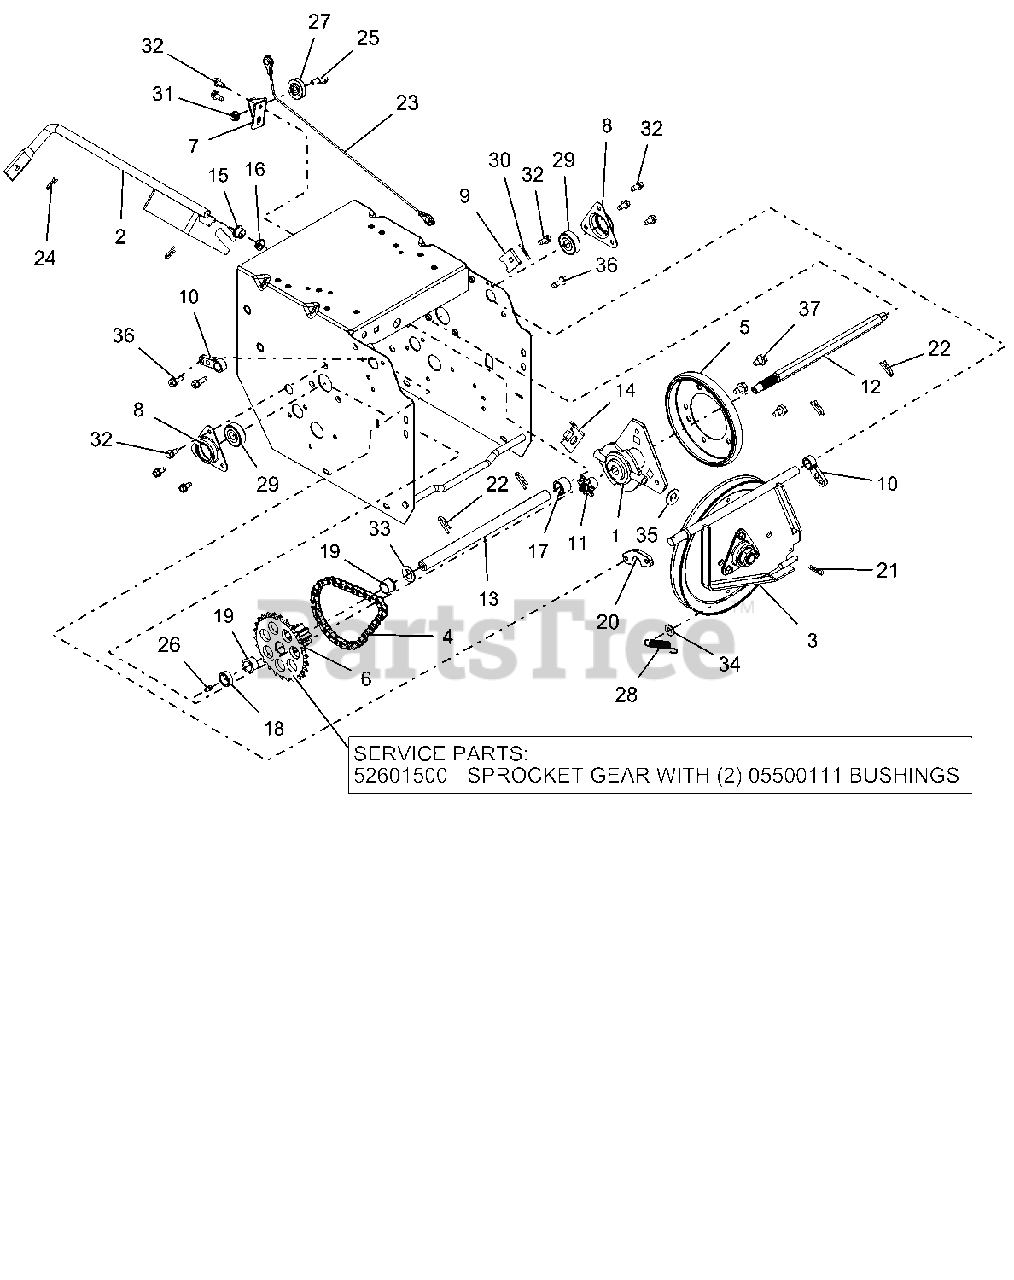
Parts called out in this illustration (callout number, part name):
1	CARRIER, DRIVE DISK
2	WELDMENT, SHIFT FORK
3	PLATE, SWING - ASSEMBLY
4	CHAIN - #41, 32 PITCHES
5	FRICTION, DISC
6	BSHG-FLG .625X.750X.500X.875
6	PINION & SPROCKET
6	PINION & SPROCKET W/BUSHINGS
7	BRACKET, CABLE PULLEY
8	FLANGE, BEARING
9	TAB, ANTI ROTATION
10	SUPPORT BUSHING, SWING GATE
11	SPROCKET, PINION 7T W/SPLINE
12	SHAFT, HEX W/SPLINE TRACK
13	SHAFT, PINION TRACK
14	BRACKET, FORMED - SHIFT FORK
15	BUSHING, POLYLINER-.50 SPLIT
16	BUSHING, POLYLINER-.50 SNAPIN
17	SPACER, .635X.880X.611
18	BSHG-SLV, .635X.880X.305
19	BSHG-FLG .625X.750X.500X.875
20	SPACER, SWING GATE
21	PIN-HAIR INT .08X.18X1.18 YWZC
22	PIN, SPRING CLIP
23	CABLE, LOWER TRACTION (DELUXE)
24	CLIP, SPRING
25	BOLT, SHLDR-.375X.375X.25-20
26	ZERK,FITTING .25X.125 DRIVE IN
27	PULLEY, CABLE
28	SPRING, EXT. .043X.438X1.64
29	BRG-BALL .437X1.375X.437
30	@PIN-GRV .125X1.00 TP E ALLOY
31	@NUT-LK-CTR-FLG .25-20 YWZC
32	SCR-TAP .25-20X.50 HWH TR YWZ
33	WSHR-FL-STL .630X1.005X.062 YZ
34	@WSHR-FL-STL.344X.688X.065YWZC
35	WSHR-FL-STL .505X1.00X.062YWZC
36	SCR-TAP-PM .25-20X.75 TR YWZ
37	@SCR-TAP .31-18X.50 HWH TR YWZ
